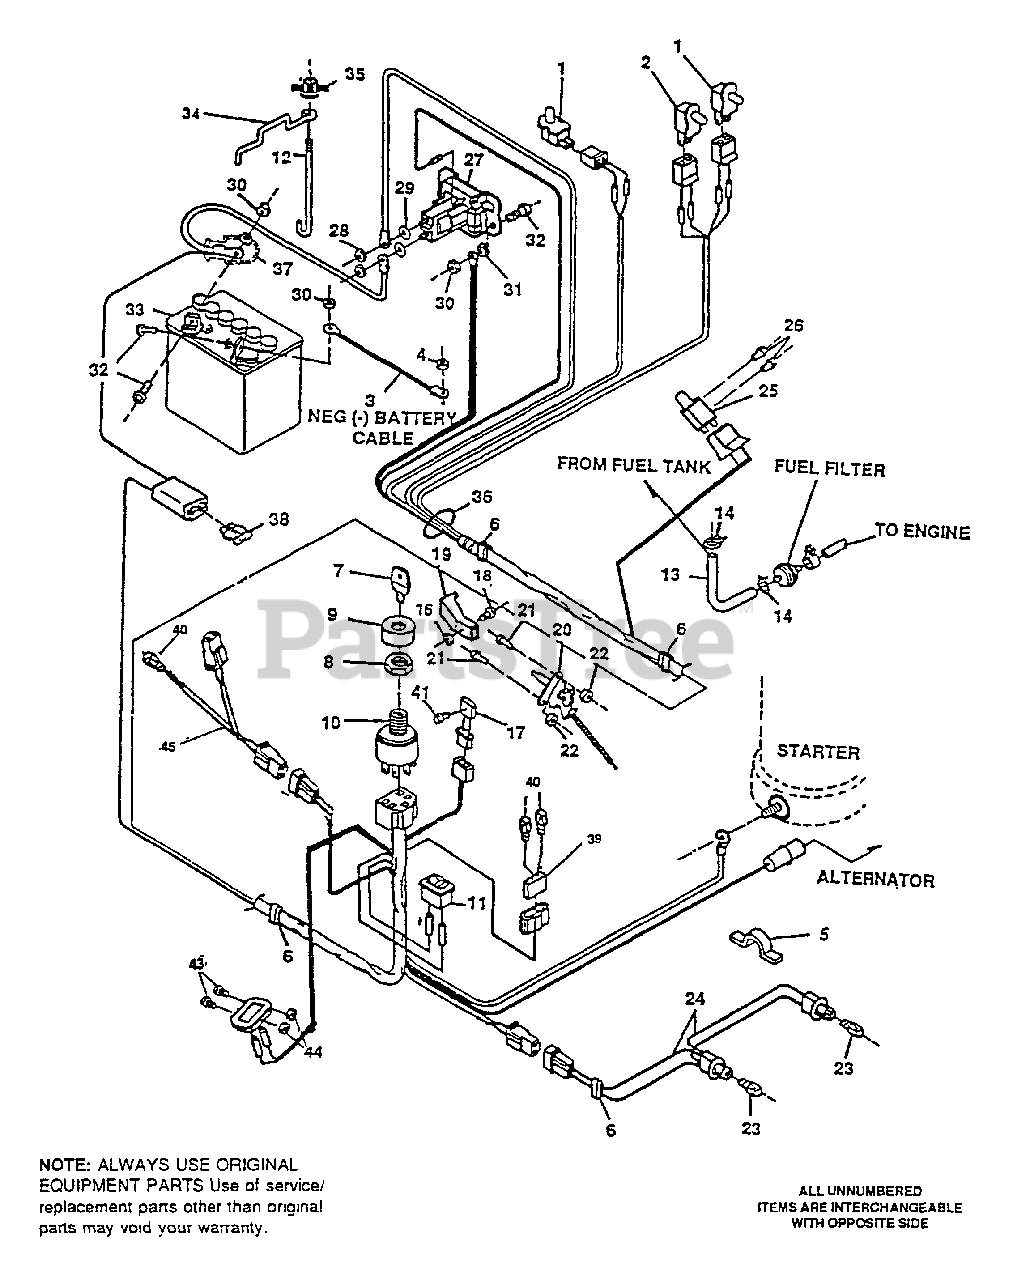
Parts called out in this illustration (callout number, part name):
1	Seat Switch
2	Deck Safety Switch
3	Ground Wire
4	Nut, Hx, Keps, 5/16-18 Thd.
5	Press Clip
6	Tie Cable
7	Key, Ignition Switch
8	Nut, Switch
9	Boot, Switch
10	Switch, Ignition
11	Switch, Light
12	Rod, Battery Hold-Down
13	Gas Line, 13-1/2" (cut to length)
14	Clamp, Gas Line
15	Screw, 1/4-20 x 5/8 In.
16	Nut, Hex, #8-32 Thd.
17	Low Voltage Sensor
18	Screw, Ph Pn, #8-32 x 3/8 In.
19	Knob, Throttle Control
20	Throttle Control
21	Screw, #10-24 X 5/8 In.
22	Nut, Hx, Nylon Lock, #10-24 Thd
23	Bulb Headlamp
24	Assembly, Light Wire
26	Screw, Pn Hd, Tap #12 x 1/2 In.
27	Solenoid
28	Nut, Hx 5/16-24 Thd.
29	Washer, Lock 5/16 In.
30	Nut, Hx, Keps, 1/4-20 Thd.
31	Nut, Hx, Ctrlk, 1/4-20 Thd.
32	Screw, 1/4-20 X 3/4 In.
34	Bracket, Battery Hold-Down
36	Wiring Harness
37	Boot, Rubber (Battery Cable)
38	Fuse, 15A-32V
39	Lamp Holder, 4-Pin (If so equipped)
40	Bulb Indicator
41	Screw, #10-1/2 Taptite
42	Hour Meter
43	Screw, #6-32 x 1/2 In.
44	Nut, #6-32 Keps
45	Low Fuel Wire
